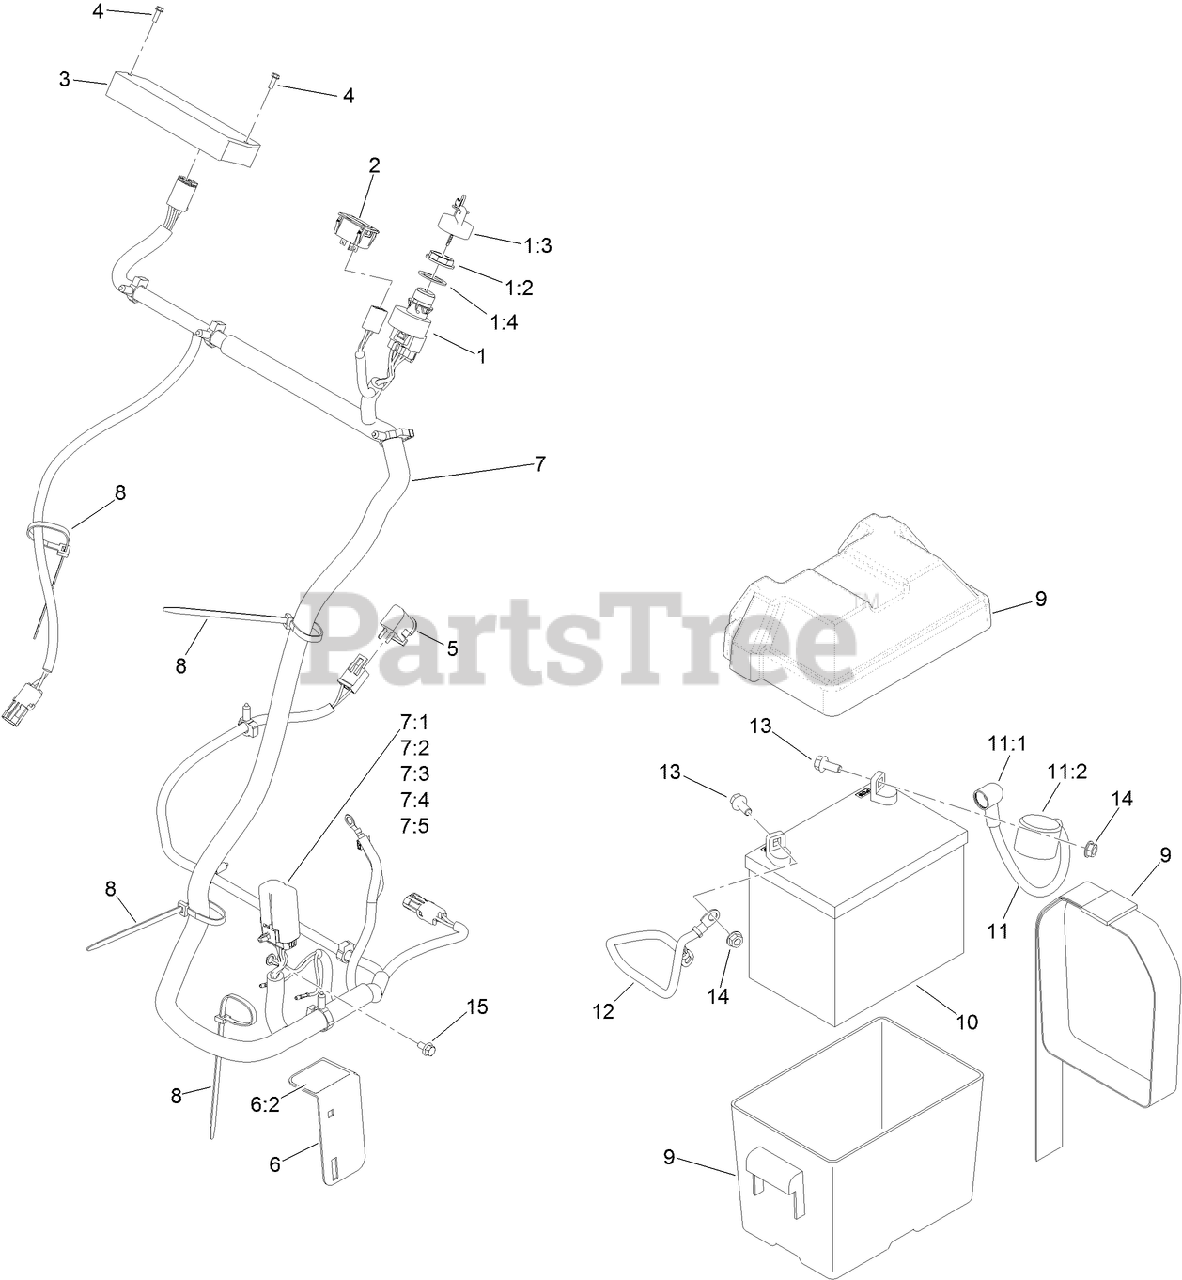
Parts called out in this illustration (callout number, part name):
1	IGNITION SWITCH ASM
1:2	NUT-MOUNTING
1:3	IGNITION KEY SET
1:4	WASHER-BACKUP
2	HOUR METER
3	CONTROLLER-DC
4	SCREW-HWHTF
5	SWITCH-BAIL
6	FUSE BRACKET ASM
6:2	DECAL-FUSE
7	HARNESS-WIRE
7:1	FUSE-MINI BLADE, 20 AMP
7:2	RELAY-MICRO
7:3	CAP-POWER DISTRIBUTION MODULE
7:4	CLIP-POWER DISTRIBUTION MODULE
7:5	BLOCK-FOAM
8	TIE-PLASTIC
9	BATTERY BOX
10	BATTERY (300 CCA, WET)
11	CABLE-BATTERY, POSITIVE
11:1	INSULATOR-SOLENOID
11:2	INSULATOR-BATTERY
12	CABLE-BATTERY, NEGATIVE
13	SCREW-HHF
14	NUT-HF
15	SCREW-HHF
